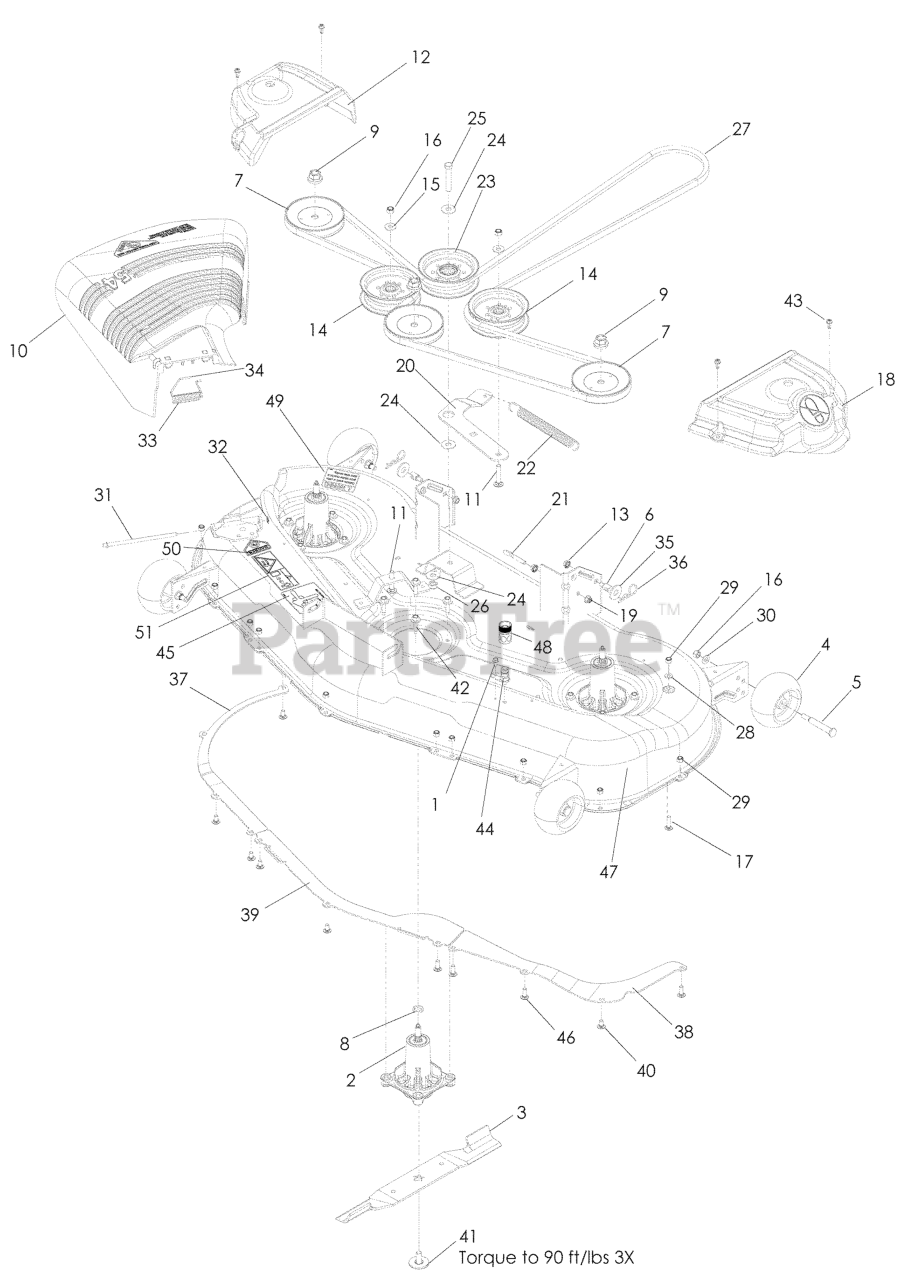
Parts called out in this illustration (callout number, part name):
1	BOLT ¼-20 x ½ HWST
2	HOUSING, CUTTER
3	BLADE, BAGGING
4	WHEEL, GAUGE
5	BOLT ½ x 25/8 SHOULDER
6	STUD, w/ANTI-ROTATE
7	PULLEY
8	WASHER/SPACER
9	NUT 9/16 TOP CNTRLK
10	DEFLECTOR, 54"
11	RHSNB 3/8-16 x 2
12	BELT SHIELD, RT
13	NUT 5/16-18 HEX WHIZLK
14	PULLEY, IDLER
15	WASHER 3/8 FLAT STD
16	NUT 3/8-16 HEX NYLOC
17	RHSNB 5/16-18 x ¾
18	BELT SHIELD, LT
19	NUT 5/16-18 FLANGE NYLOC
20	ARM, IDLER
21	EYE BOLT 5/16 x 3½
22	SPRING, DECK BELT
23	PULLEY, IDLER
24	WASHER 7/16 FLAT
25	HCS 7/16-14 x 2½
26	NUT 7/16-14 HEX
27	BELT.DECK.52".54"
28	WASHER 5/16 SAE FLAT
29	NUT 5/16-18 HEX NYLOC
30	WASHER 3/8 SAE FLT
31	ROD, HINGE
32	PUSHNUT
33	SPRING, TORSION
34	CAP, SLEEVE
35	WASHER ½ FLAT
36	HAIRPIN #4
37	BAFFLE, RIGHT 54
38	BAFFLE, LEFT 54"
39	BAFFLE, CENTER 54"
40	RHSNB 5/16-18 x 5/8
41	BOLT WASHER ASSM
42	SCREW 5/16-18 x WSHER HD
43	SCREW ¼-20 x 5/8 THDROLL
44	PORT, WASHOUT
45	DECAL, BELT ROUTING
46	RHSNB 5/16-18 x 1
47	DECK w/ DECALS
48	COUPLING, QUICK CONN
49	DECAL, WARNING
50	DECAL, WARNING
51	DECAL, SEVERING
